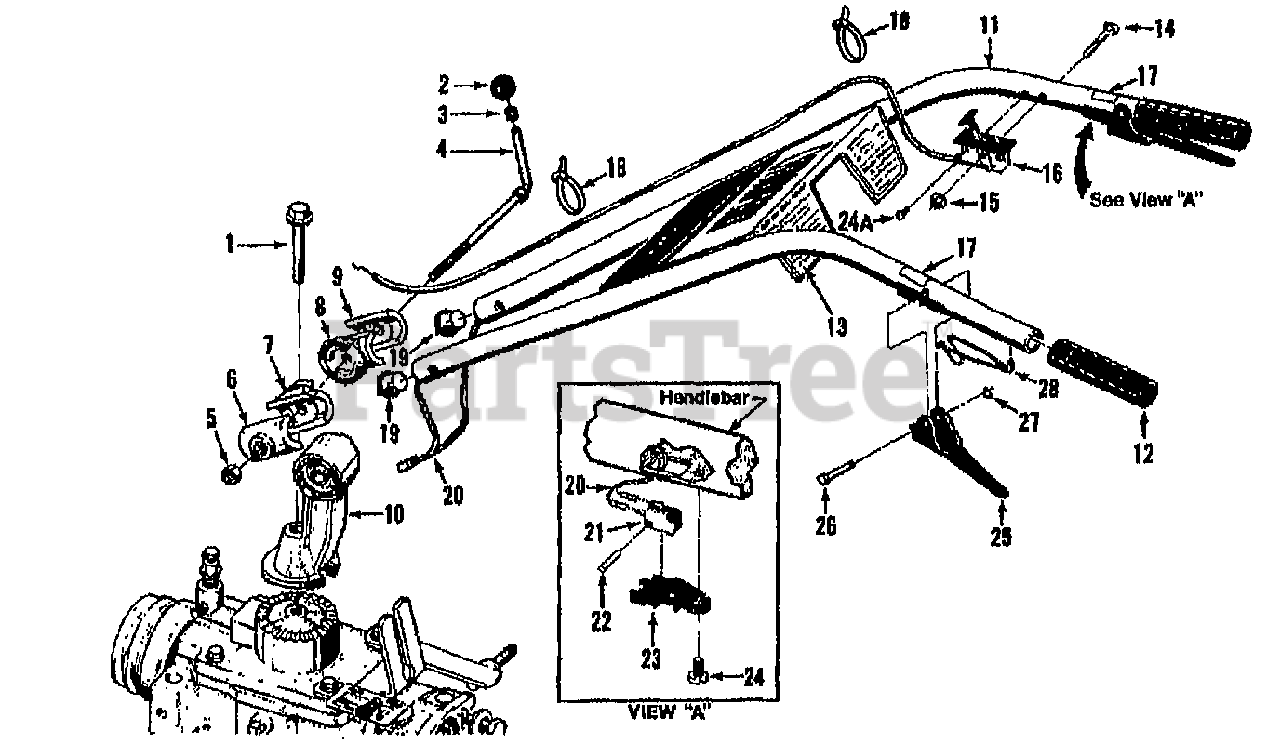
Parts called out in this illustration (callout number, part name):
1	BOLT 1/2-13X3.5 FH GR5
2	KNOB-CONTROL (INCL. 3)
3	RING-TOLERANCE .5325 ID
4	STUD-H/BAR W/NUT & RING (INCL. 2,3 & 5)
5	NUT-HEX JAM 1/2-13
6	CLAMP-LH HORSE 1021-1
7	RATCHET-H/BAR RED 2542-1
8	RATCHET-RH RED HORSE 2542-2
9	CLAMP-RH HORSE 1021-2
10	BASE-H/BAR RED 2534A
11	ASSM-HANDLEBAR W/GRIPS (INCL. 2 OF EA. 12, 17 & 28 AND ONE 13)
12	GRIP-H/BAR SMOOTH
13	DECAL-CONTROL PANEL HORSE
13	DECAL-CONTROL PANEL (11HP)
14	BOLT-CH 1/4-20X2.00 ZP
15	NUT-HF/LK 1/4-20 ZP
16	CABLE-THROTTLE 7 I/C B&S {12068/069/080/081/087}
16	CABLE-THROTTLE 7&8 B&S {12074/075/088/089/090}
16	CABLE-THROTTLE 8HP OPC {12070/071/082/083}
17	DECAL-FWD INTERLOCK
18	TIE-RED
19	RETAINER-HARNESS H/B OPC
20	HARNESS-WIRE OPC HORSE
21	SWITCH-H/B OPC
22	PIN-LK .11X.58 HORSE OPC
23	HOUSING-SWITCH OPC
24	SCR-HW M10-24X.5 STH ZP
24A	SCR-PHS M10-32X.5 STH ZP
25	LEVER-HORSE OPC
26	PIN-PIVOT OPC LEVER
27	RING-KLIP 5304-25
28	SPRING-H/B LEVER
